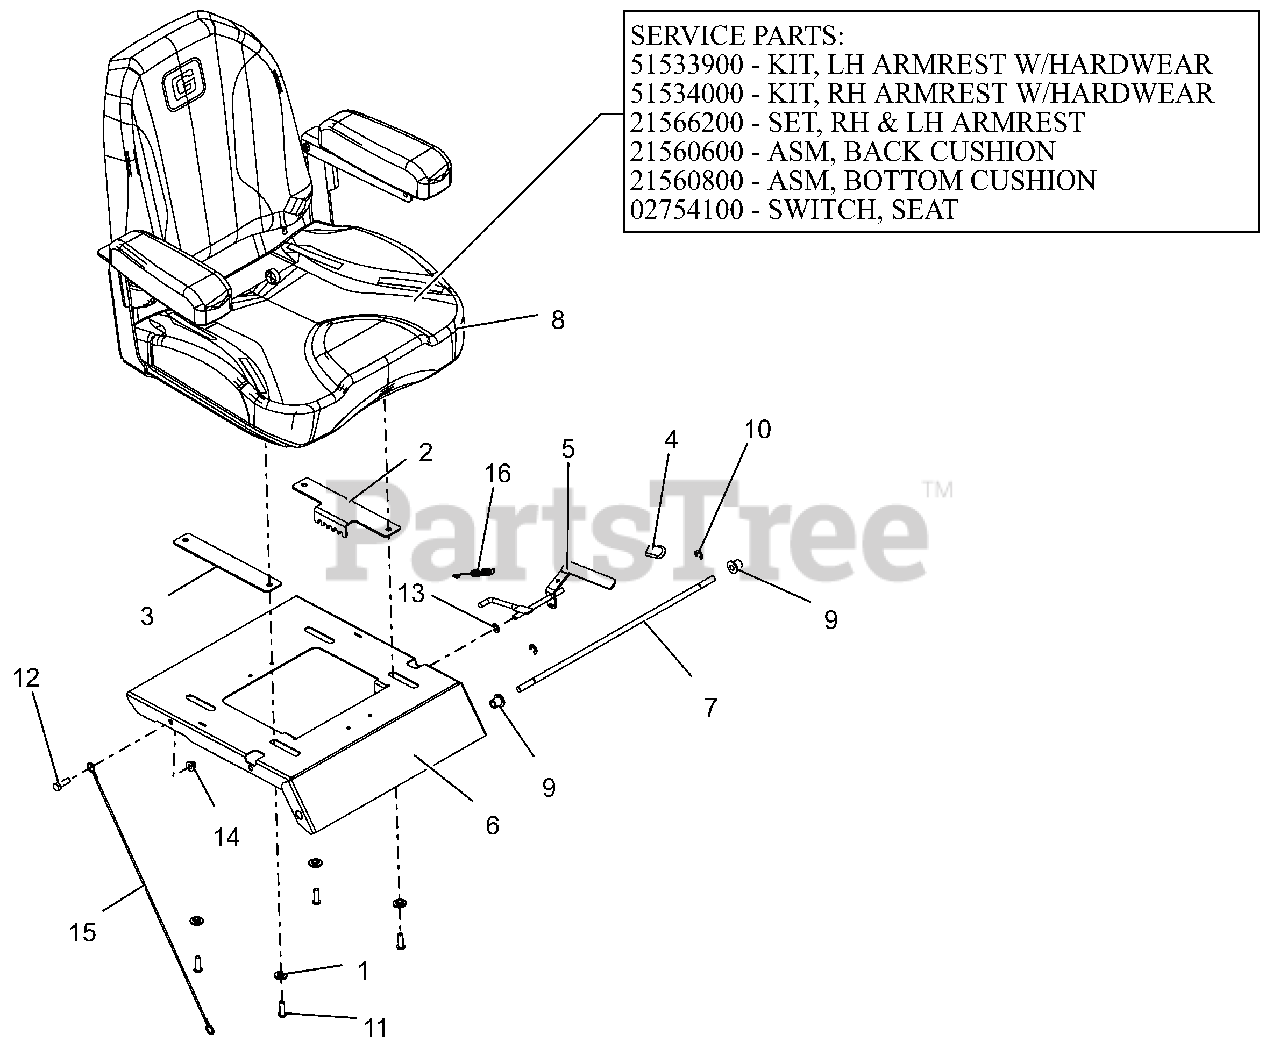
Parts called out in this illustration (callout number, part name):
1	BSHG, FLG .325X.499X.26X.88
2	PLATE, ADJUSTABLE SEAT TRACK
3	PLATE, ADJUSTABLE SEAT SLIDE
4	GRIP, SEAT LEVER, GREY
5	WLDMT, ADJUSTABLE SEAT LATCH
6	PLATE, SEAT
7	ROD, SEAT PIVOT
8	SEAT, ZTXL 2018
8	KIT, ARMREST LH W/HDWR
8	KIT, ARMREST RH W/HDWR
8	SET, RH & LH ARMREST ASM
8	ASM, BACK CUSHION-GRAVELY XL
8	ASM,BOTTOM CUSHION-GRAVELY XL
8	SWITCH- SNAP MTG N.O.
9	BSHG-FLG .38X.580X.667X.750
10	RG-RTNG-EXT .375X.035 TYP E
11	BLT,SHCS-BTN .31-18X1.00 ZCC
12	BLT,HEX .31-18X1.00 G5 ZCC
13	NUT-PUSH .312
14	NUT,NYL-FLG .31-18 GF ZCC
15	LANYARD, SEAT CABLE .093X19.5
16	SG-TENS .043X.44X3.31 WLD 5.8
